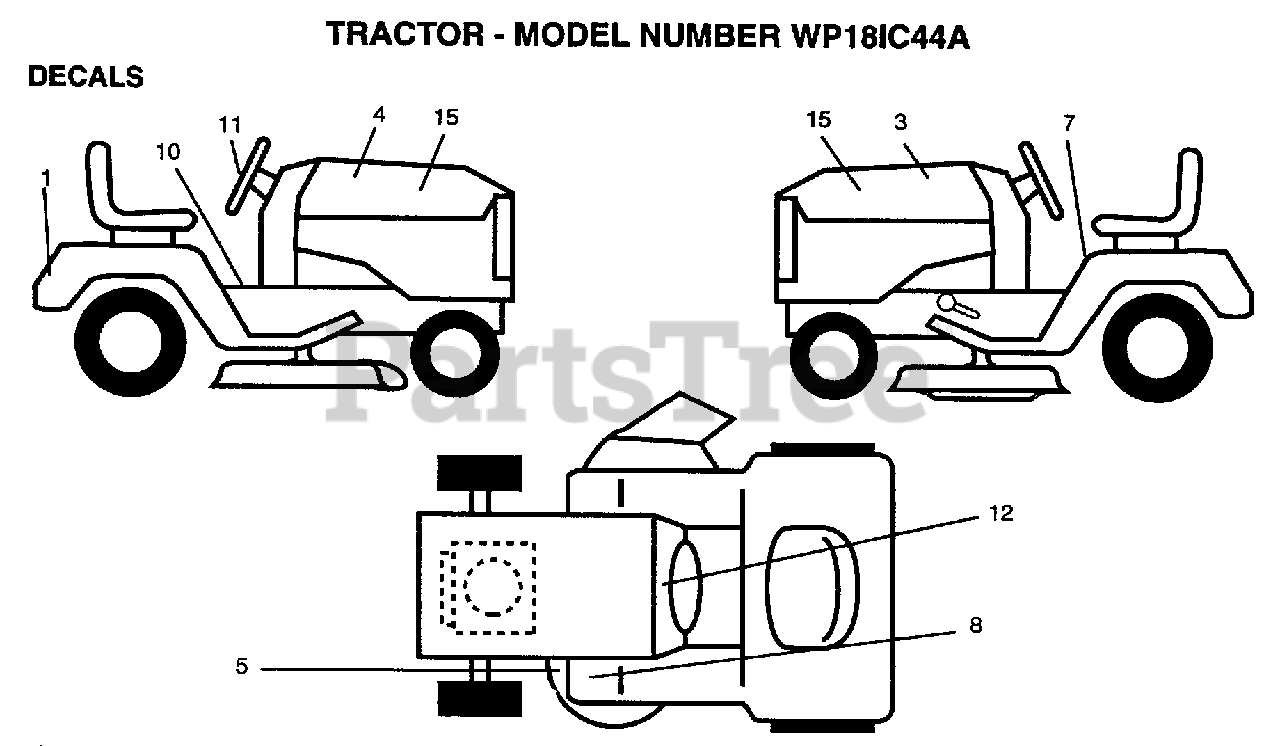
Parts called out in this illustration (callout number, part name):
1	DECAL, FENDER LOGO
3	DECAL.HOOD.LH
4	DECAL.HOOD.RH
5	"DECAL.V.BELT.44"""
7	DECAL
10	DECAL BRAK PARK
11	DECAL, INSERT
12	DECAL.DASH.INST.
15	DECAL.INS.HD.LT.
